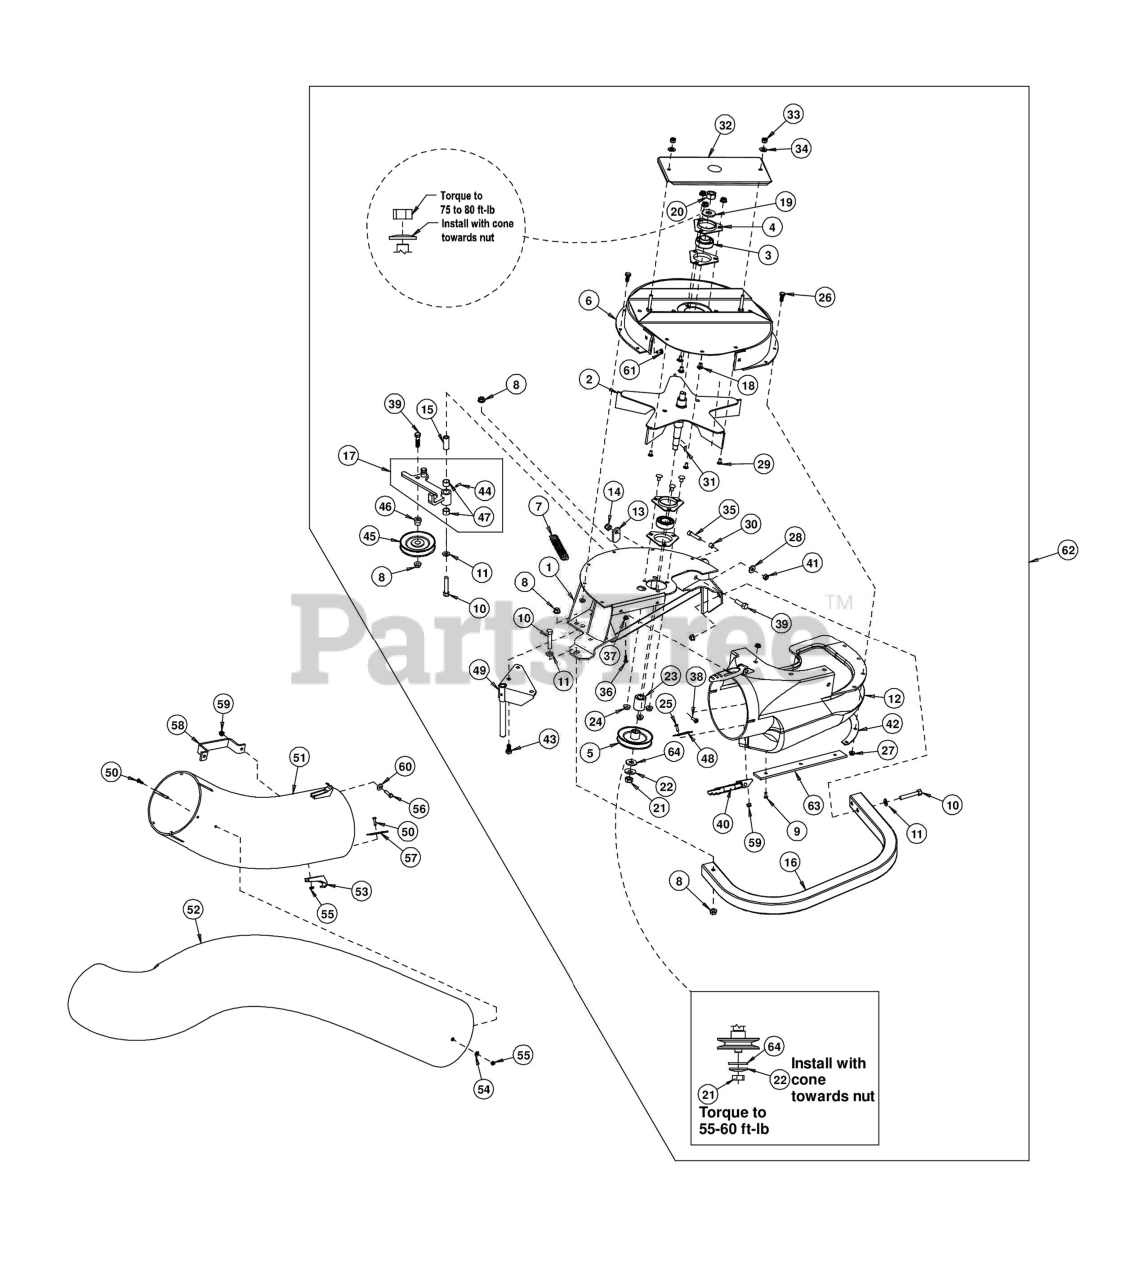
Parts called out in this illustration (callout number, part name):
1	WLD,BLOWER MOUNT
2	IMPELLER
3	BEARING
4	HOUSING-FLANGE
5	SHEAVE
6	ASM, UPPER HSG
7	SPRING-IDLER
8	NUT-HHF, WHIZ
9	RIVET-BLIND
10	SCREW-HH
11	WASHER-FLAT
12	ASM,BLOWER CHUTE LZ
13	LATCH-CATCHER, GRASS
14	NUT-LOCK, NI
15	BUSHING
17	ASM, IDLER ARM - SERVICE
18	SCREW-CARR
19	WASHER-SPRING
20	NUT-HEX
21	NUT-JAM
22	WASHER-SPRING
25	SCREW-HH
26	SCREW-HH
28	WASHER-SPRING
29	SCREW-CARR
30	BUSHING, LOCATOR
31	KEY-WOODRUFF
32	ASM, BEARING COVER
33	NUT-LOCK, NI
34	WASHER-FLAT
35	SCREW-HSH
36	SCREW-HEAD, TRUSS
39	SCREW-HH
40	LATCH-RUBBER
41	NUT-HEX
42	PLATE-BACKING, BLOWER
43	SCREW-HH
44	FITTING-GREASE
46	HUB,SPACER
47	BUSHING
48	PLATE-BACKING
49	PIN-MOUNT
50	SCREW-HWH
51	TUBE-LOWER
52	TUBE-UPPER
53	LATCH-CATCH
54	WASHER-FLAT
55	NUT-LOCK, NI
56	SCREW-HH
57	PLATE-BACKING
59	NUT-LOCK, NI
60	WASHER-FLAT
61	BOLT-CARR
62	Asm, Blower (Includes Items 1-49,61, 63 & Decals) .
63	PLATE,REINFORCEMENT LARGE
64	WASHER-FLAT
65	NUT-LOCK, NI
